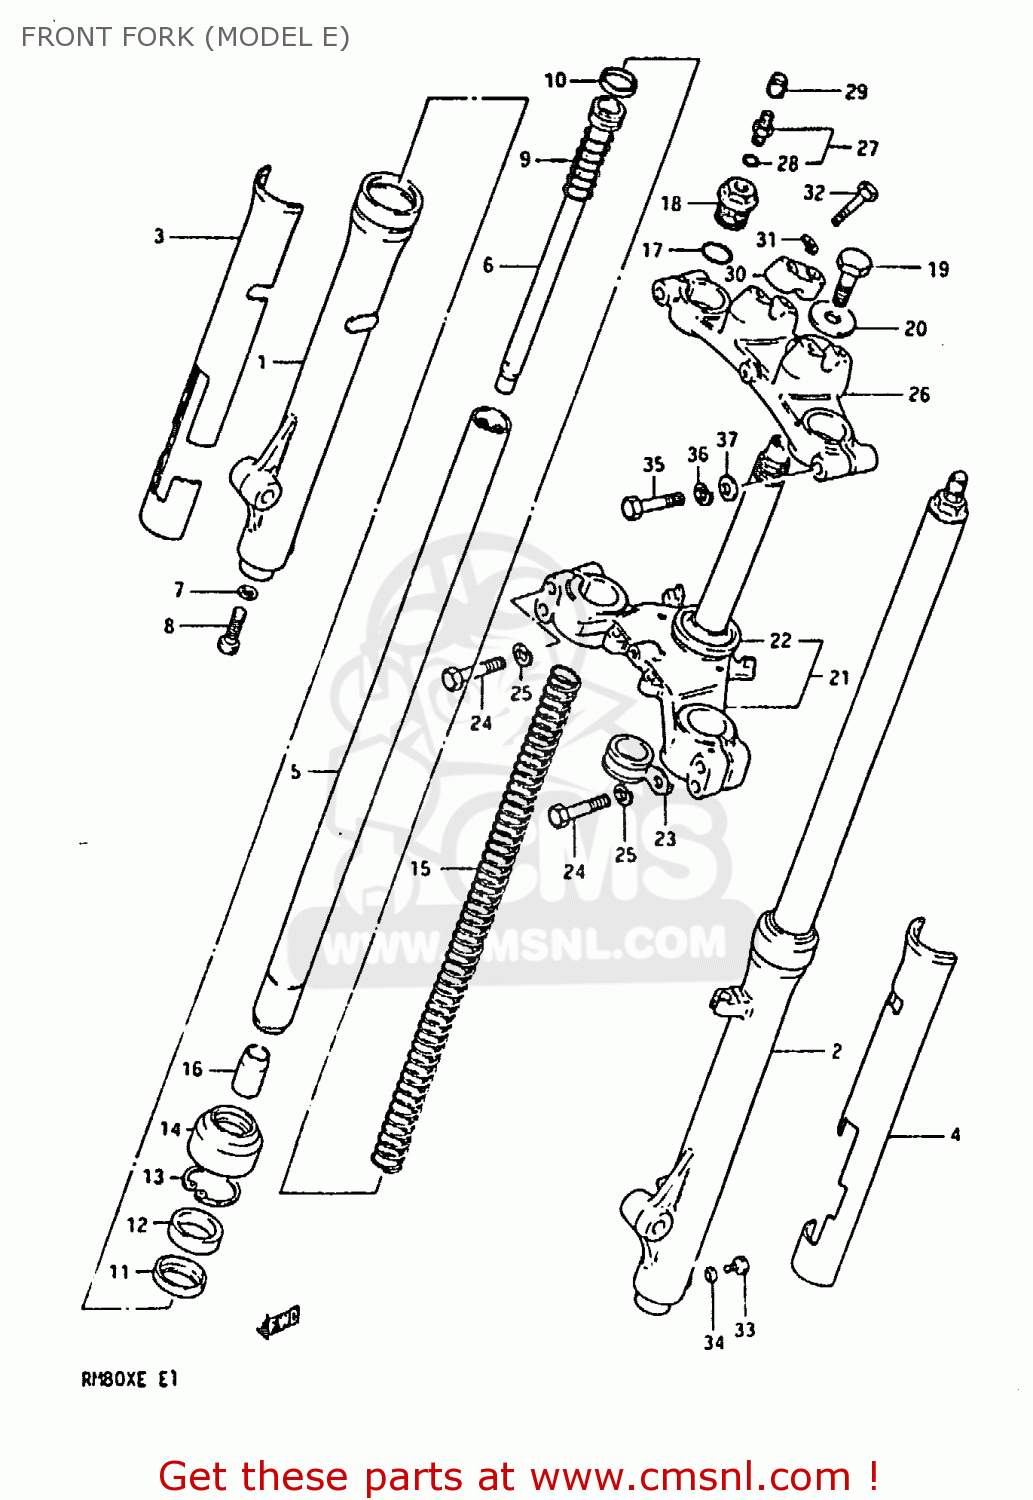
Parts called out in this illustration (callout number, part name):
1	TUBE,OUTER,RIGHT
2	TUBE,OUTER,LEFT
3	PROTECTOR,FRONT FORK,RIGHT
4	PROTECTOR,FRONT FORK,LEFT
5	TUBE,INNER
6	CYLINDER,FRONT FORK
7	GASKET (NAS)
8	BOLT(8X27)
9	SPRING,REBOUND
10	RING,PISTON
11	SPACER,FORK OIL SEAL
12	SEAL,OIL
13	CIRCLIP,FORK OIL SEAL
14	SEAL,DUST
15	SPRING,FRONT FORK
16	PIECE,OIL LOCK
17	O RING
18	BOLT,FORK INNER TUBE
19	BOLT,STEERING STEM HEAD
20	WASHER,STEERING STEM
21	STEM,STEERING
22	RACE,STEERING OUTER LWR
23	GUIDE,CABLE
24	BOLT,FORK INNER TUBE F
25	LOCK WASHER
26	HEAD,STEERING STEM
27	VALVE,AIR
28	O-RING
29	CAP
30	HOLDER,HANDLEBAR
31	LOCK WASHER
32	BOLT
33	BOLT
34	GASKET,DRAIN,PLUG (NAS)
35	BOLT 8X40
36	LOCK WASHER
37	WASHER
